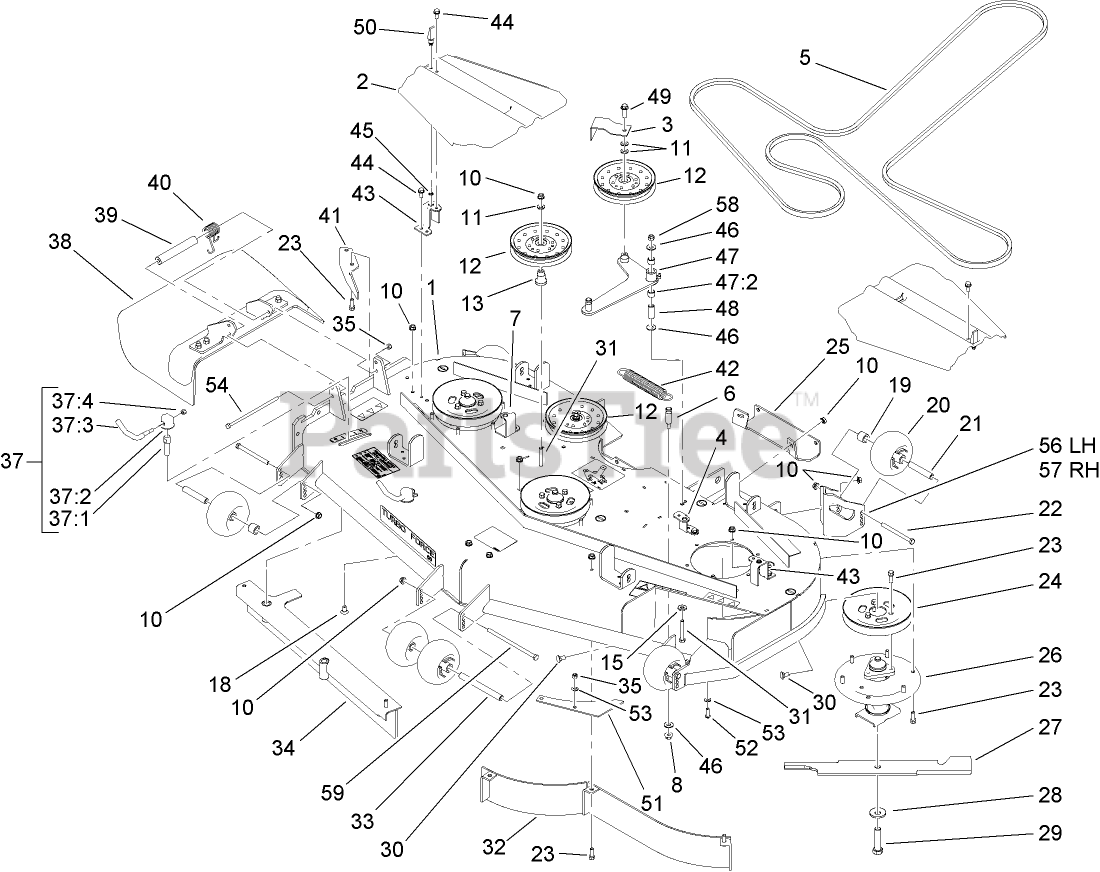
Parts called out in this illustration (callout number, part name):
1	DECK DECAL ASM
2	COVER-BELT
3	GUIDE-BELT
4	BRACKET-COVER, TALL
5	BELT-V
6	PIN-THREADED, SPRING ANCHOR
7	BRACKET-COVER
8	NUT-HF
10	NUT-HHF, WHIZ
11	WASHER-FLAT
12	Idler-Flat
13	MOUNT-PULLEY
15	WASHER-BELLEVILLE
18	SCREW-CARR
19	TUBE-SPACER
20	ROLLER-SCALP, ANTI
21	TUBE-SPANNER
22	SCREW-HH
23	SCREW-HWH
24	PULLEY
25	Plate-Skid
26	Spindle ASM
27	BLADE-HI FLOW
28	Washer-Blade Bolt, Heavy
29	Screw-Cap
30	SCREW-CARR
31	SCREW-HH
33	SPACER-WHEEL
35	NUT-LOCK, NI
37	LEVER ASM
37:1	Screw-Lock
37:2	CAP-LOCK
37:3	Lever-Lock
37:4	NUT-LOCK, NI
38	RUBBER DEFLECTOR ASM
39	SPACER
40	SPRING-TORSION
41	BAFFLE-DISCHARGE
42	SPRING-EXTENSION
43	BRACKET-COVER
44	SCREW-HWHTF
45	WASHER
46	WASHER-FLAT
47	DECK IDLER ARM ASM
47:2	SLEEVE-BEARING
48	BUSHING
49	SCREW-HHF
50	LATCH-SWELL
51	PLATE-TURBO
52	SCREW-HSBH
53	WASHER-SPRING
54	SCREW-HH
56	MOUNT-WHEEL, LH
57	MOUNT-WHEEL, RH
58	NUT-LOCK, NI
59	SCREW-HH
